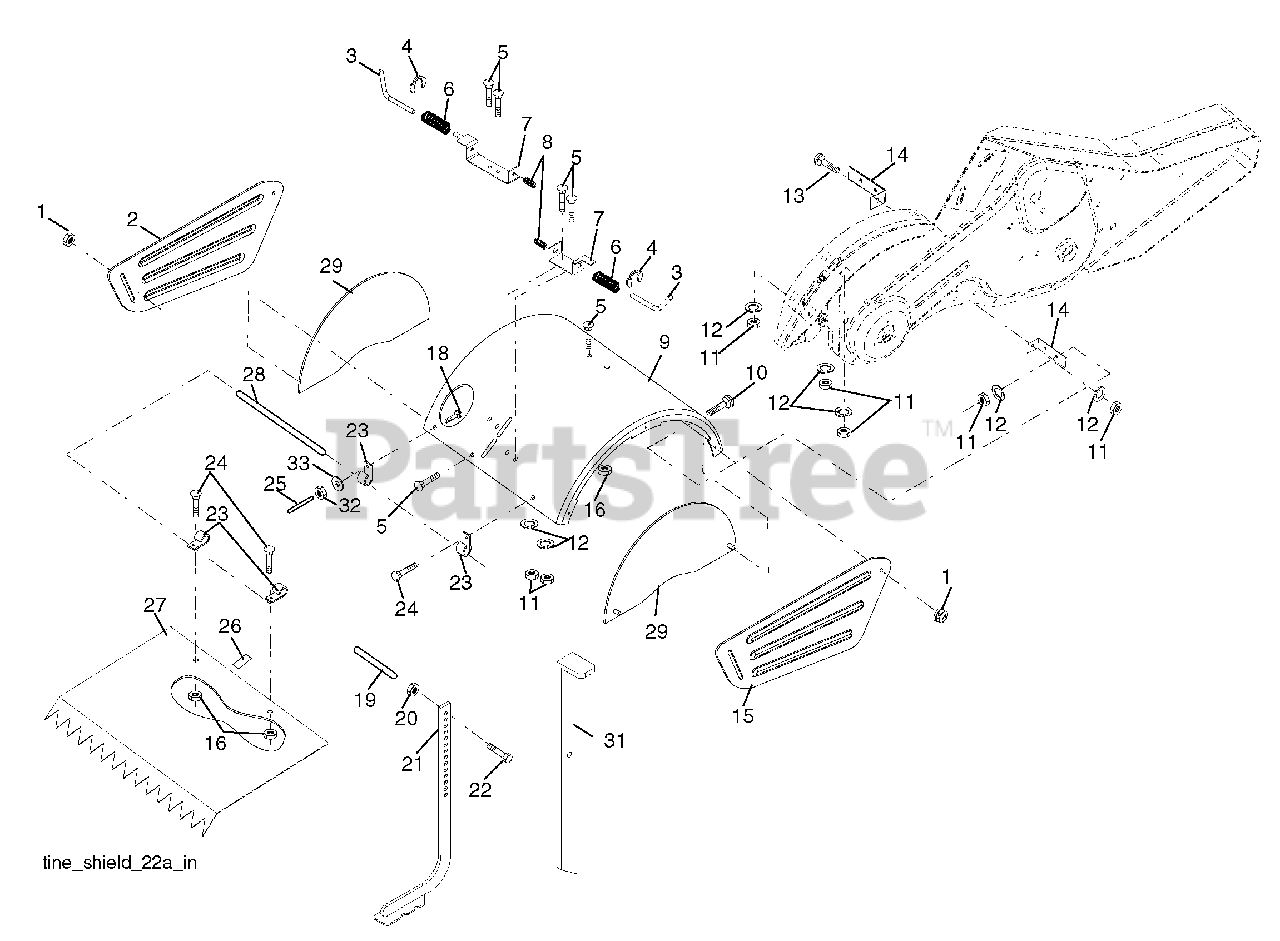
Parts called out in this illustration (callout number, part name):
1	Nut, Lock Hex Flange 5/16-18 unc
2	Shield, Side, Outer L. H.
3	Pin, Stake, Depth
4	Ring, Klip
5	Bolt Rdhd Sqnk 5/16-18 x 3/4
6	Spring
7	Bracket, Latch
8	Spring, Depth Stake
9	Shield, Tine
10	Bolt 5/16-18 x 1
11	Washer, Lock 5/16
12	Nut, Hex 5/16-18
13	Bolt, Carriage 5/16-18 x 1-1/4
14	Bracket, Shield Tine
15	Shield, Side, Outer R.H.
16	Nut, Hex Flange 1/4-20
18	Bolt, Carriage 1/4-20 x 1-1/4 Gr. 5
19	Grip
20	Nut, Hex 3/8-16
21	Stake, Depth
22	Bolt, Hex 3/8-16 x 2
23	Hinge
24	Bolt, Carriage 1/4-20 x 1/2
25	Cap, Vinyl
26	Pad, Idler
27	Shield, Leveling
28	Pin, Hinge
29	Shield, Side
31	Stake, Drag
32	Nut, Fin, Hex 1/4-20 unc
33	Washer Lock Hvy Helical 1/4
